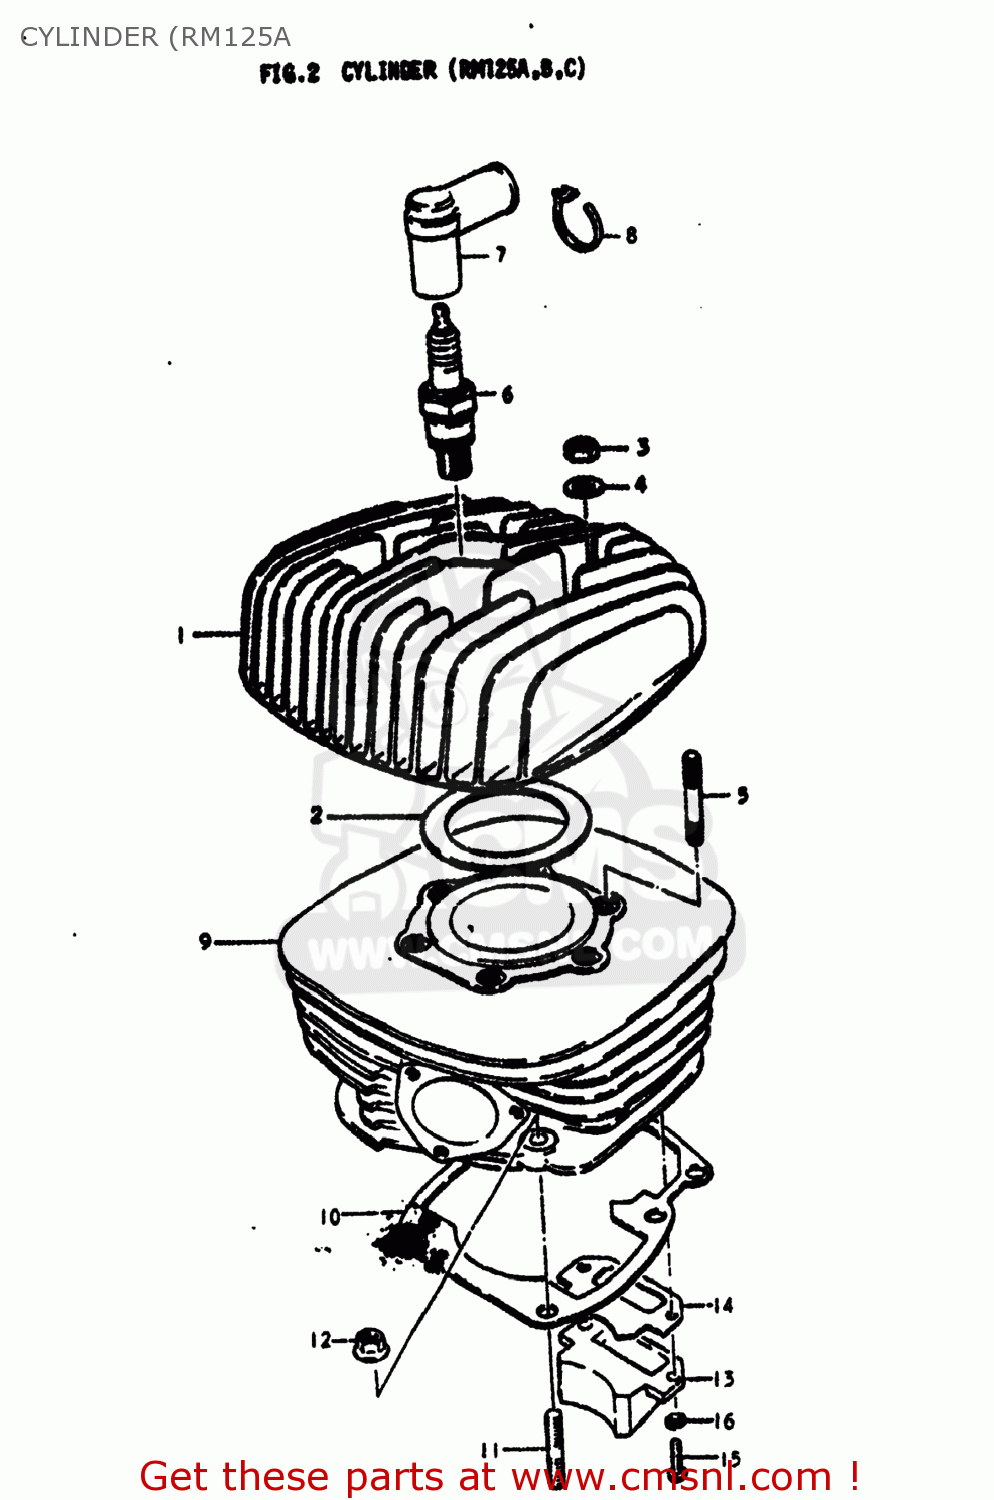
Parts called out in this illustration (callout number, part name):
1	HEAD,CYLINDER
2	GASKET,CYLINDER HEAD (NAS)
3	NUT (8MM)
4	WASHER
5	STUD BOLT
6	SPARK PLUG
7	CAP,SPARK PLUG
8	CLAMP
9	CYLINDER
10	GASKET,CYLINDER (MCA)
11	STUD 8X25
12	NUT
13	VALVE ASSEMBLY,REED
14	GASKET,REED VALVE (MCA)
15	SCREW
16	LOCK WASHER
